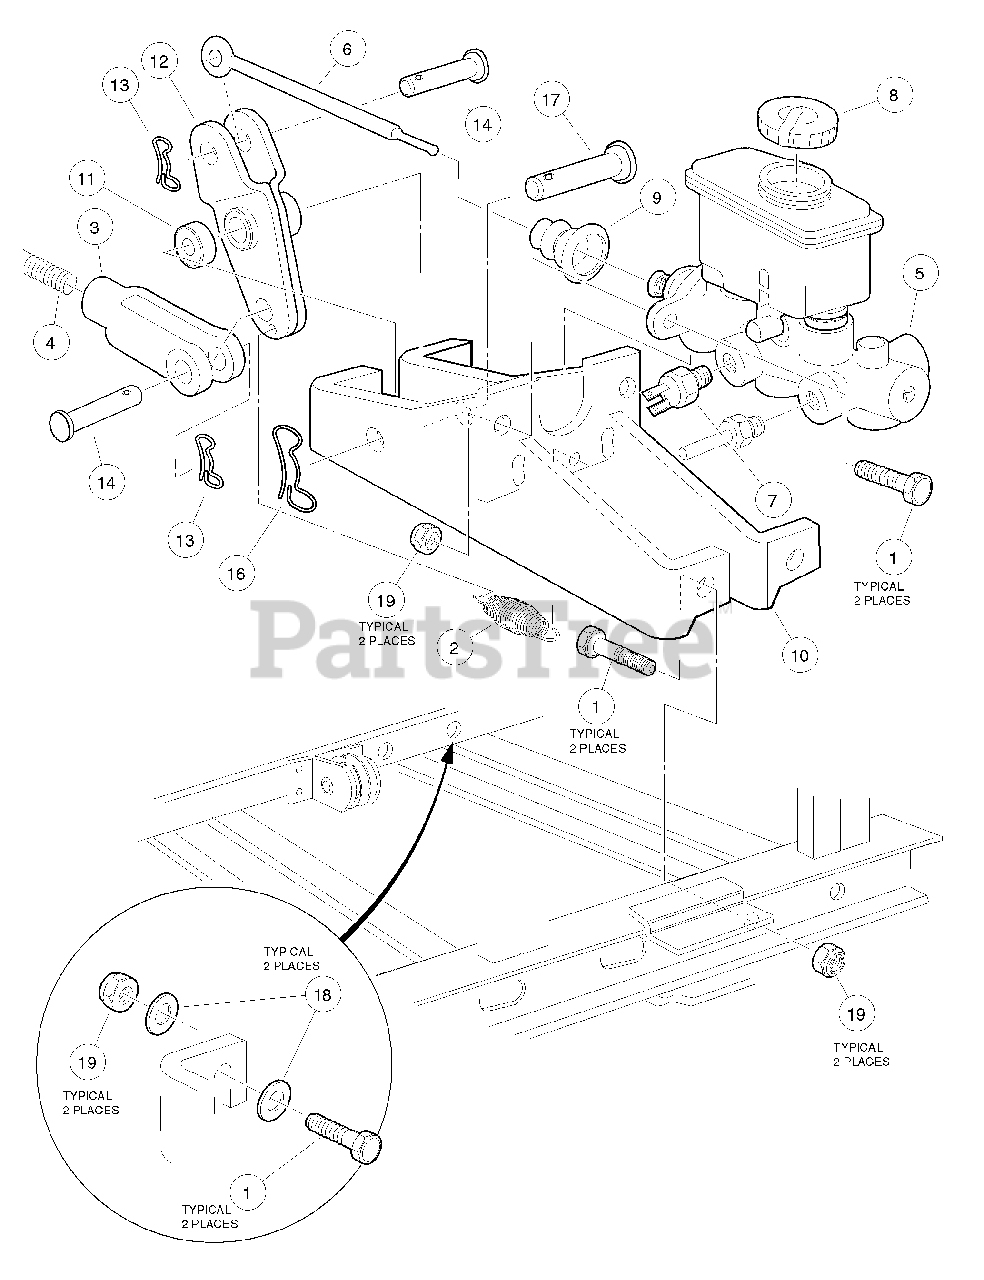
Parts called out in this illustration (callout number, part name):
1	Screw, 5/16-18 X 100 Hex Cap
2	Spring, Brake Return
4	Rod, Equalizer, 1330"
5	Master Cylinder
7	Pressure Switch
8	Filler Cap Asm
9	Master Cylinder Boot
10	Support Leg Brace Asm
12	Bell Crank
13	Pin, Bow Tie Locking
14	Pin, 3/8 X 1-5/16 Clevis
15	Plug, 3/8 X 24
16	Pin, Bow Tie 0120 X 2750
17	Pin, 1/2 X 2-1/2 Clevis
18	Washer, 5/16 Type A Flat
19	Locknut, 5/16-18 Nylon Insert
